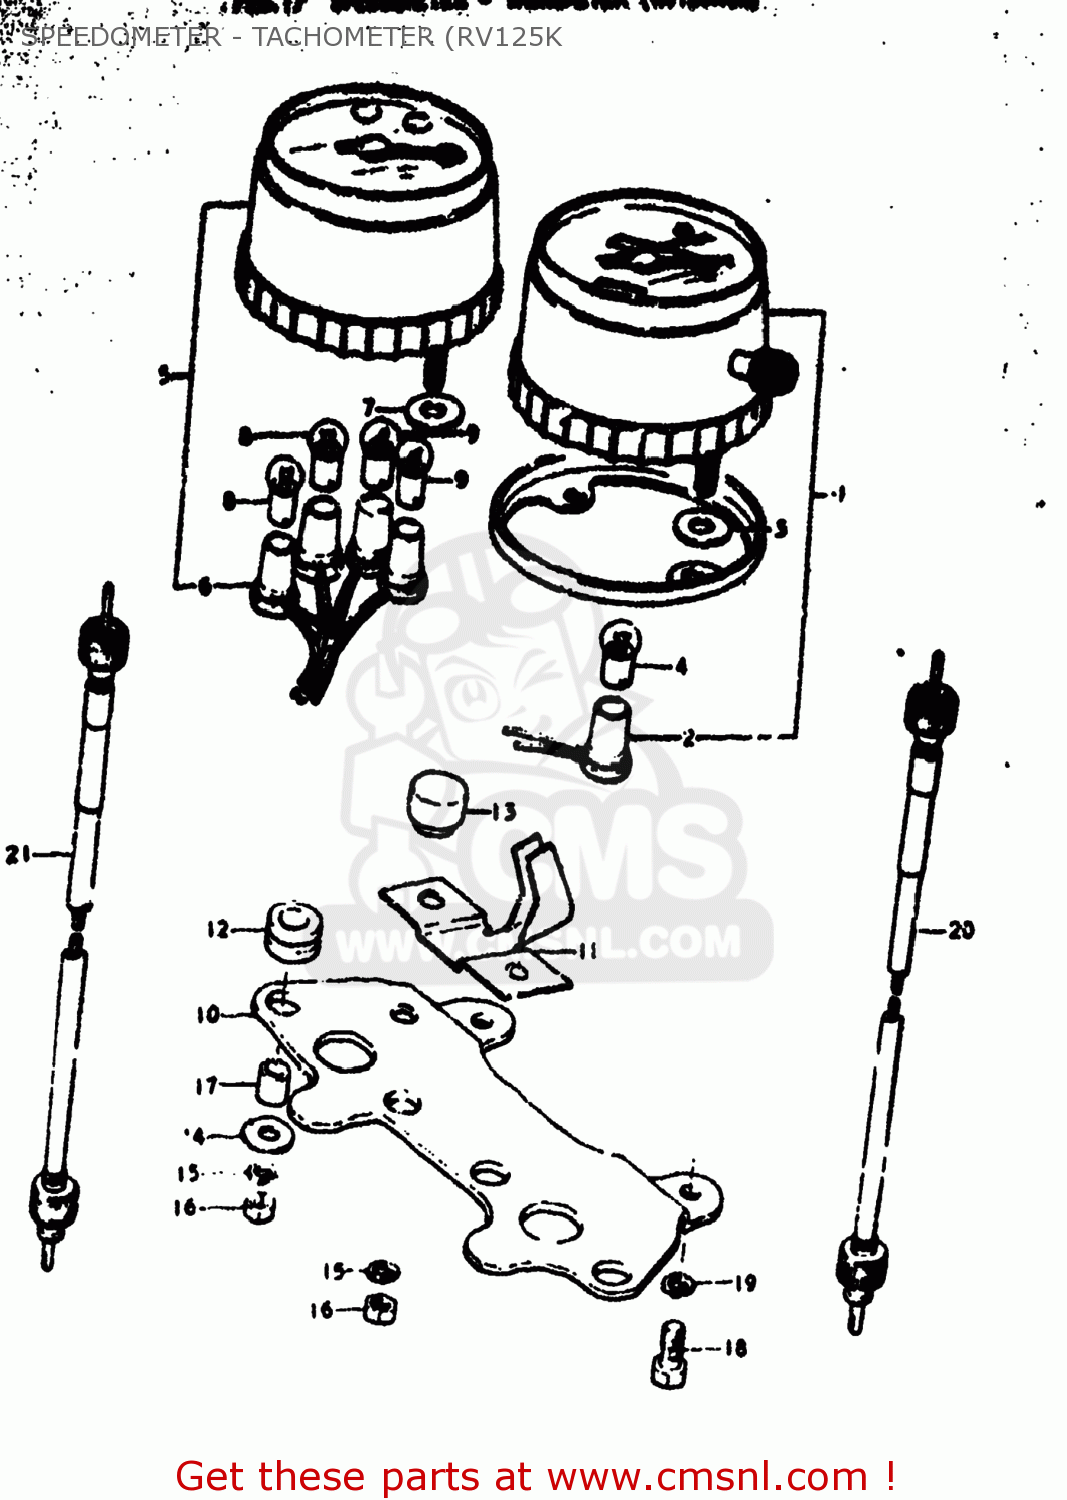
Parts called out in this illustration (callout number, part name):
1	SPEEDOMETER ASSEMBLY
2	SOCKET,METER
3	WASHER (5.5X16X1.2)
4	BULB(6V/3W)
5	TACHOMETER ASSEMBLY
6	SOCKET,TACHOMETER
7	WASHER (5.5X16X1.2)
8	BULB(6V/3W)
9	BULB(6V1.7W,STANLEY,A61A)
10	BRACKET,METER
11	COVER,METER,UNDER
12	CUSHION
13	CUSHION,METER
14	WASHER (5.5X16X1.2)
15	LOCK WASHER
16	NUT
17	SPACER,METER NO.2
18	BOLT
19	LOCK WASHER
20	CABLE ASSY,SPEEDOMETER
21	CABLE ASSEMBLY,TACHOMETER
